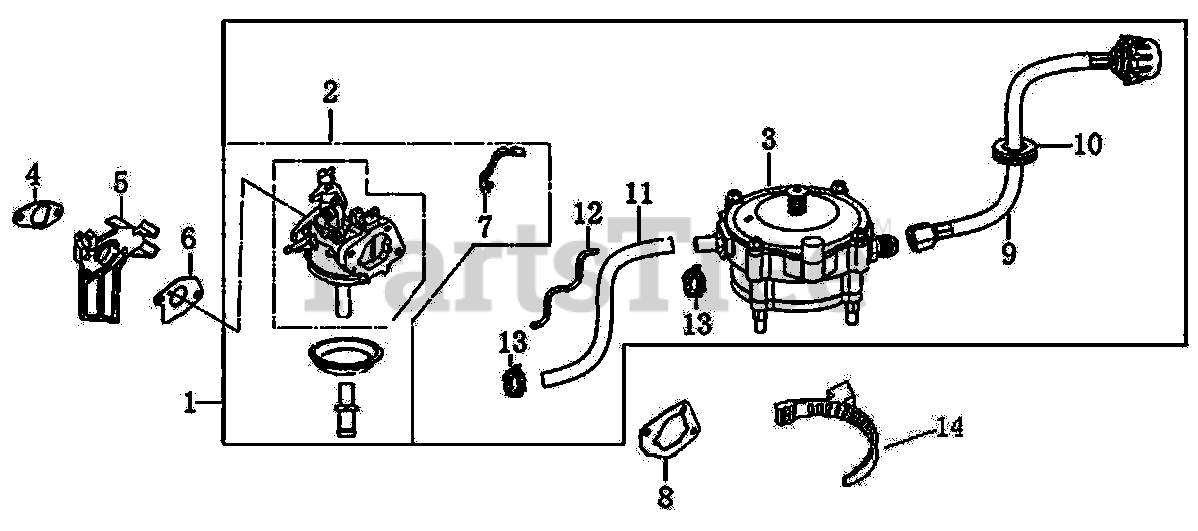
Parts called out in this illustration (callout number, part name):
0J5785A	REGULATOR, HIGH PRESS., 180 DEGREE
1	REDUCTION VALVE
2	CARBURETOR
3	REGULATOR, HIGH PRESS., 90 DEGREE
4	GASKET, INSULATOR
5	INSULATOR, CARBURETOR
6	GASKET., CARBURETOR
7	LEVER ASSY,CHOKE
8	GASKET, AIR CLEANER
9	PIPE (HOSE, FUEL LP TANK)
10	GROMMET
11	PIPE (HOSE, FUEL LP REGULATOR)
12	PIPE (HOSE, Vent)
13	CLIP, TUBE
